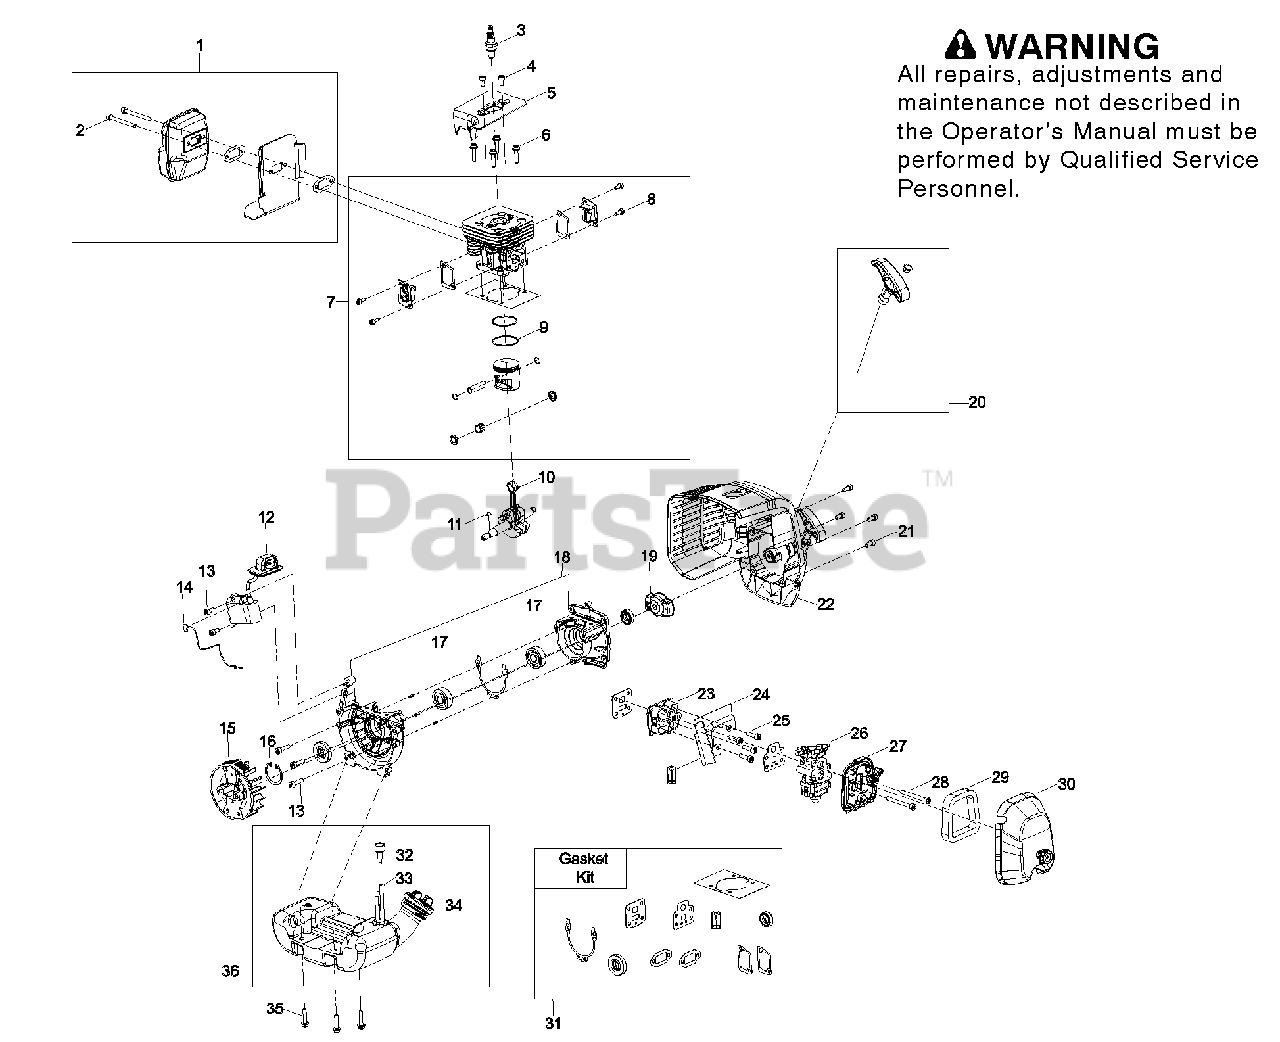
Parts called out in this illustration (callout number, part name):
1	Kit - Muffler
2	Screw (2 pack) (9SXMBJ05-50)
3	Spark Plug
4	Screw (4 pack) (9SGEB-05-10)
5	Plate (spark side)
6	Screw (4 pack) (9SRCB-05-22)
7	Kit - Cylinder / Piston
8	Screw (4 pack) (9SGEB-04-10)
9	Ring - Piston
10	Assembly - Crankshaft & Rod
12	Ignition Coil (9288-320601-CH)
13	Screw (5 pack) (9SGEB-05-20)
14	Coil Wire
15	Flywheel
17	Bearing (2 pack) (9DB-620101)
18	Assembly - Crankcase
19	Assembly - Pawls
20	Kit - Rope & Handle
21	Screw (4 pack) (9SGKB-05-12.5)
22	Assembly - Starter Housing
23	Insulator
25	Screw (4 pack) (9SKKB-05-19)
26	Carburetor
27	Assembly - Filter Base (with choke lever)
28	Screw (2 pack) (9SGEB-05-52)
30	Assembly - Filter (with knob)
31	Kit - Gasket
32	Kit - Vent
33	Kit - Fuel Line & Filter
34	Assembly - Fuel Cap with retainer
35	Screw (6 pack) (9SKKBY05-18)
36	Assembly - Fuel Tank
